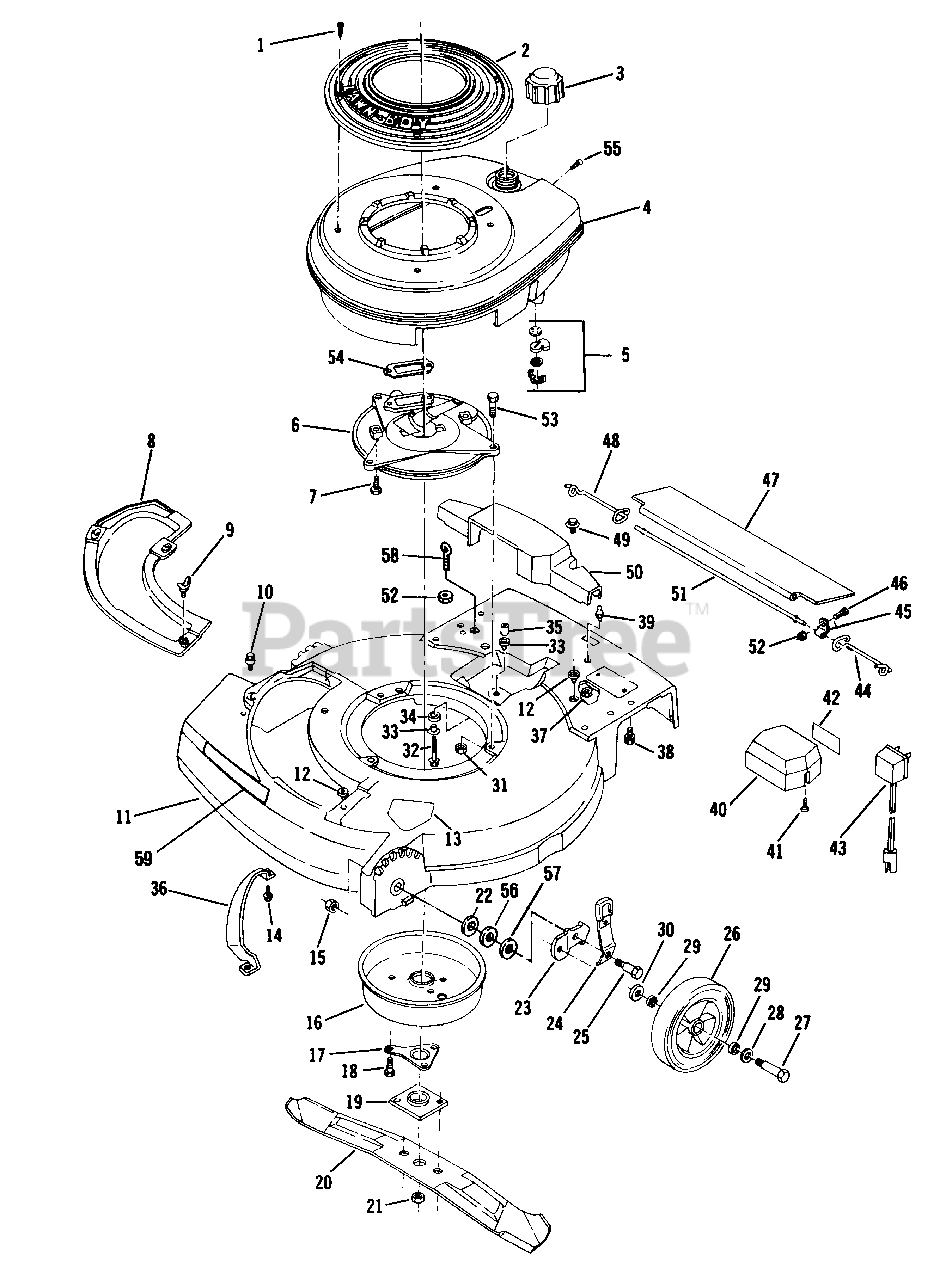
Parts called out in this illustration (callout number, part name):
1	Screw
2	Cover-Shroud
4	Shroud-Engine
5	Fuel Shut-Off Assembly
6	Plate-Muffler
7	Screw-Muff. Plt. to Blk.
8	Cover Plate
9	Wing Screw
10	Screw Plt. and Chute Mtg.
11	Housing
12	Grommet
13	Decal-Blade Contact Warning
14	Screw
15	Nut
16	Muffler Cover Assembly
17	Support-Crankshaft
18	Screw-Muff. to Muff. Plt.
19	Collar and Plate Assembly
20	Blade-21"
21	Nut-Blade
22	Washer
23	Bracket-Whl. Hgt. Adj.
24	Knob and Spring Assembly
25	Bolt-Shoulder
26	Wheel-Front
27	Bolt-Wheel-Front
28	Washer
29	Washer-Felt
30	Washer
31	Nut-Muff. Plt. to Housing
32	Screw
33	Spacer
34	Grommet
35	Spacer
36	Toe Bar
37	Nut-Ball Stud
38	Screw-Handle Bracket
39	Ball Stud-Batt. Mounting
40	Batt. Box and Batt. Pack Ass'y.
41	Screw
42	Decal
43	Battery Charger Assembly
44	Spring-L.H.
45	Clamp
46	Screw
47	Shield-Trailing
48	Spring-R.H.
49	Screw-Axle Cover Mounting
50	Cover-Drive Axle
51	Rod-Trailing Shield
52	Nut-Trailing Shield and Eyebolt
53	Screw-Muff. Plt. to Hsg.
54	Gasket-Exhaust
55	Screw-Shroud to C.D. Brk't.
56	Washer-Shim-Wheel Height Adj. Bracket
57	Washer-Shim-Wheel Height Adj. Bracket
58	Eyebolt-Starter Rope
59	Decal-Headliner
